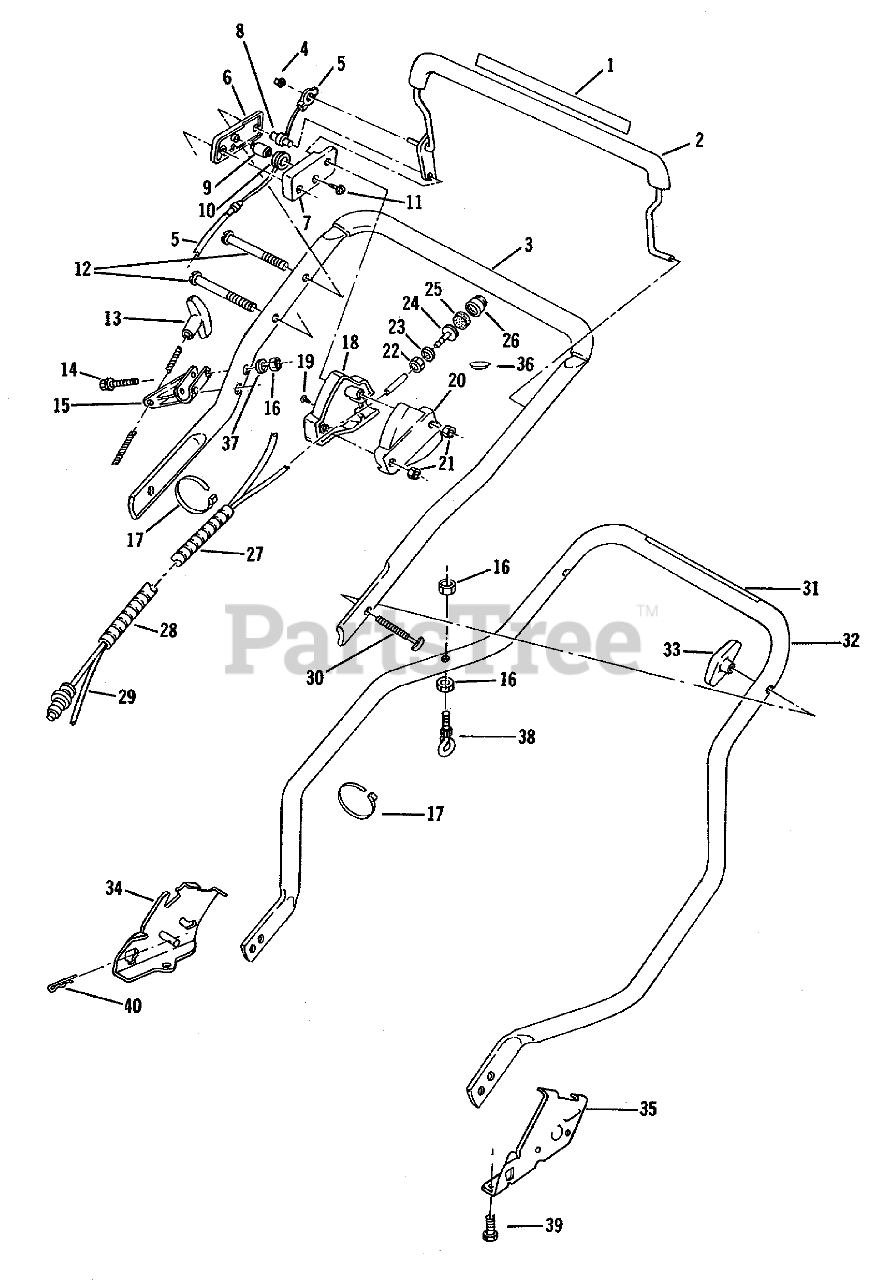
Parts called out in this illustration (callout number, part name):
8	COLUMN
9	PIN SKF
11	SCREW
13	HANDLE,STARTER
16	LOCKNUT E
21	NUT C/LOCK E
22	LOCKNUT S
25	FILTER S
30	BOLT QUALITY
33	NUT-WING
37	WASHER
38	EYE BOLT WAS MFG
39	SCREW
40	HAIR PIN
